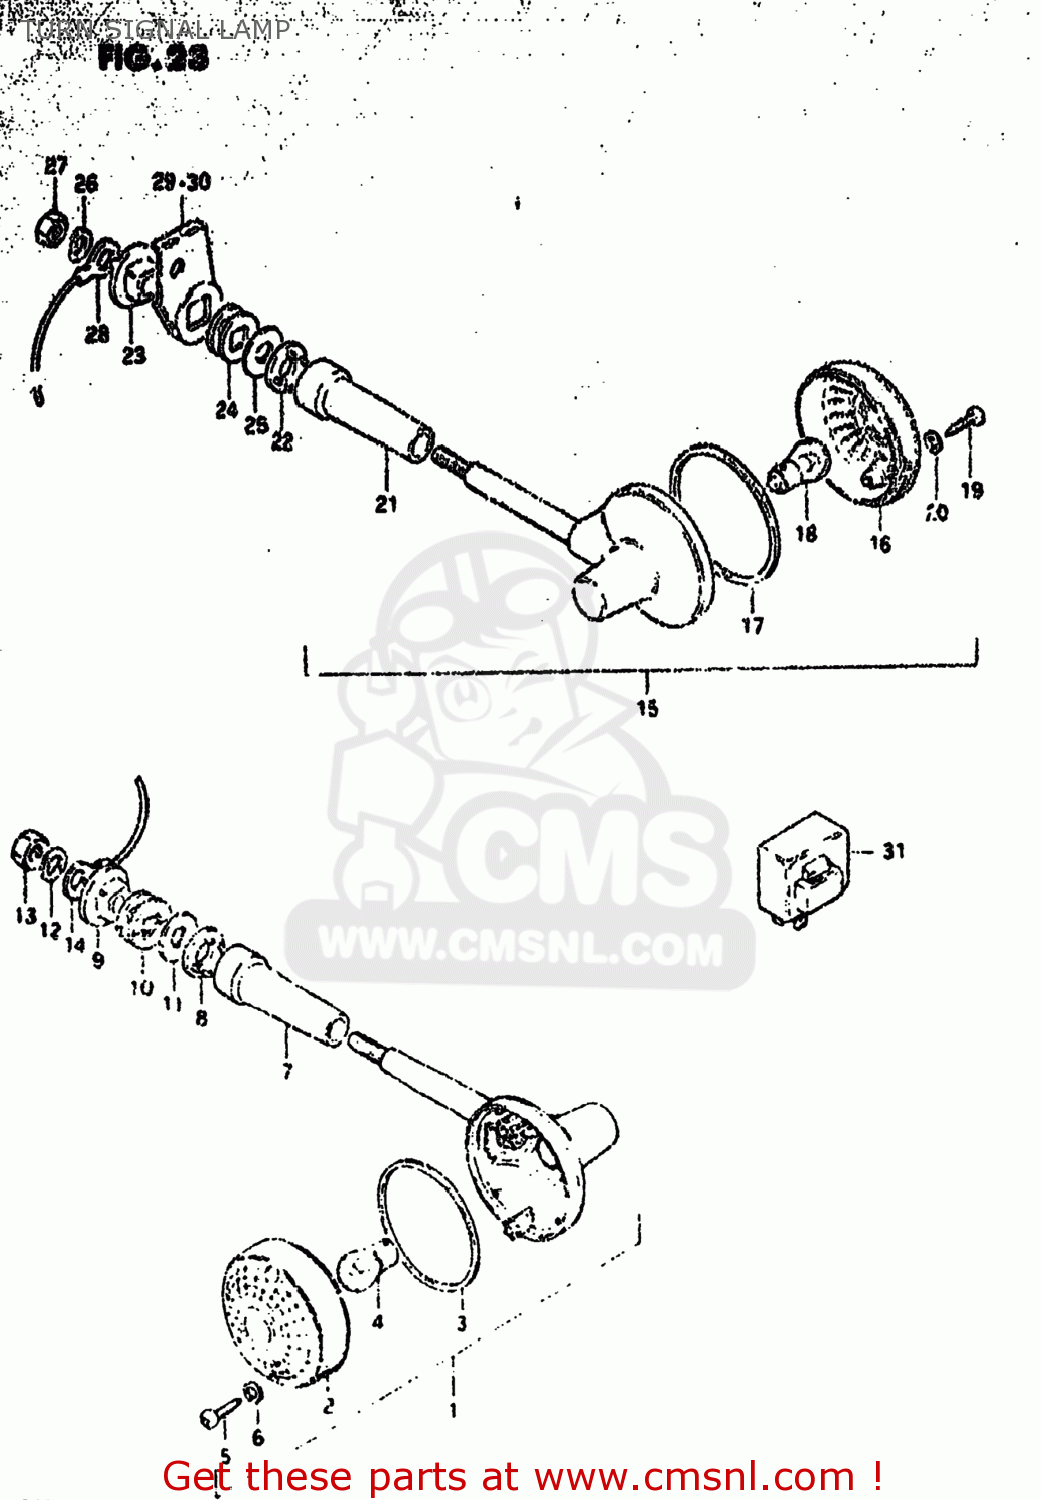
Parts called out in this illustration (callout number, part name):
1	LAMP ASSEMBLY,REAR TURN SIGNAL
2	LENS
3	GASKET (NAS)
4	BULB(12V23W,STANLEY,A4577A)
5	SCREW
6	GASKET (NAS)
7	COVER,STAY
8	SPACER
9	SPACER
10	CUSHION
11	WASHER (10.5X30X2.3)
12	LOCK WASHER
13	NUT
14	WIRE
15	LAMP ASSEMBLY,REAR TURN SIGNAL
16	LENS
17	GASKET (NAS)
18	BULB(12V23W,STANLEY,A4577A)
19	SCREW
20	GASKET (NAS)
21	COVER,STAY
22	SPACER
23	SPACER
24	CUSHION
25	WASHER (10.5X30X2.3)
26	LOCK WASHER
27	NUT
28	WIRE
29	BRACKET,REAR TURN SIGNAL
30	BRACKET,REAR TURN SIGNAL
31	RELAY,TURN SIGNAL
